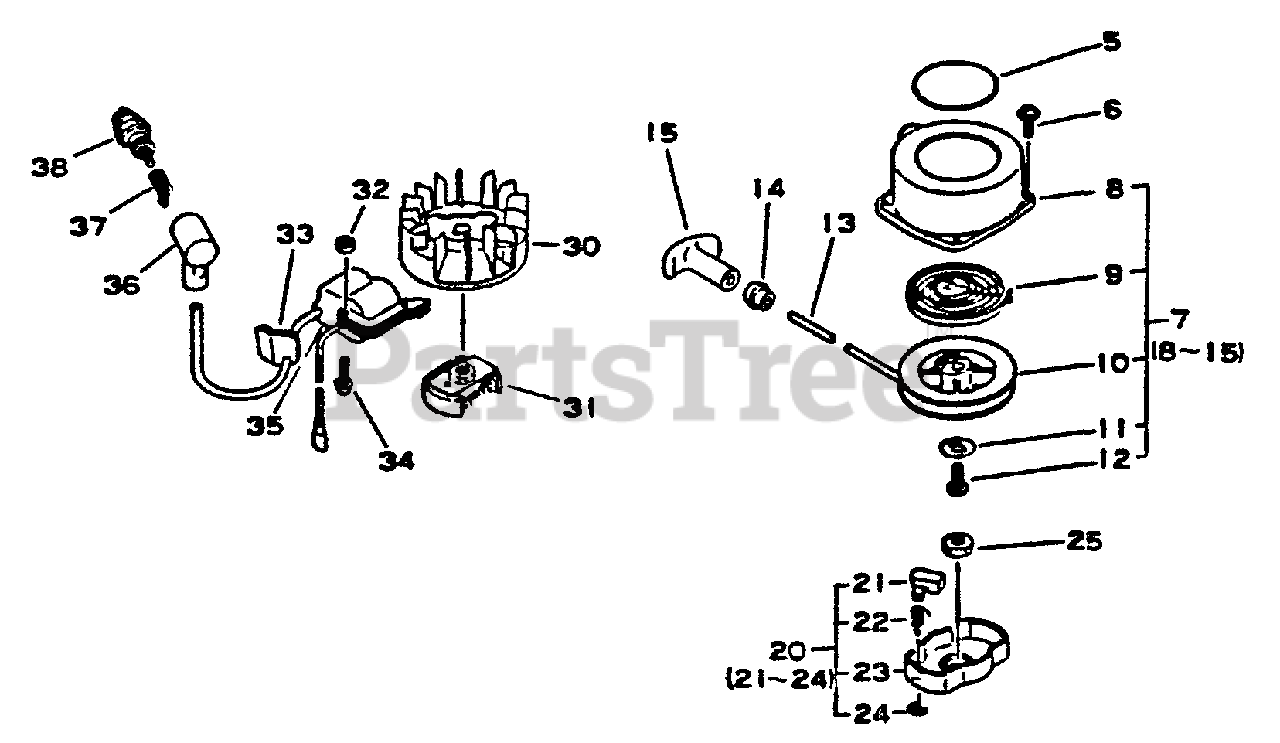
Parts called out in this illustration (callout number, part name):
5	LABEL - ECHO
6	SCREW - 4X16
7	STARTER ASSY
8	CASE, STARTER
9	SPRING, REWIND
10	REEL, ROPE
11	WASHER
13	ROPE, STARTER - 3X890
14	GUIDE, ROPE
15	GRIP, STARTER
20	STARTER PAWL ASSY
21	PAWL, STARTER
22	SPRING, RETURN
23	CATCHER, PAWL
24	RING, RETAINING - 6
30	FLYWHEEL
31	CLUTCH ASSY
33	COVER, DUST
34	SCREW - 4X22
35	COIL, IGNITION
36	CAP, SPARK PLUG
37	TERMINAL, SPARK PLUG CAP
38	SPARK PLUG -- BM-6A
38	SPARK PLUG -- BMR-6A
